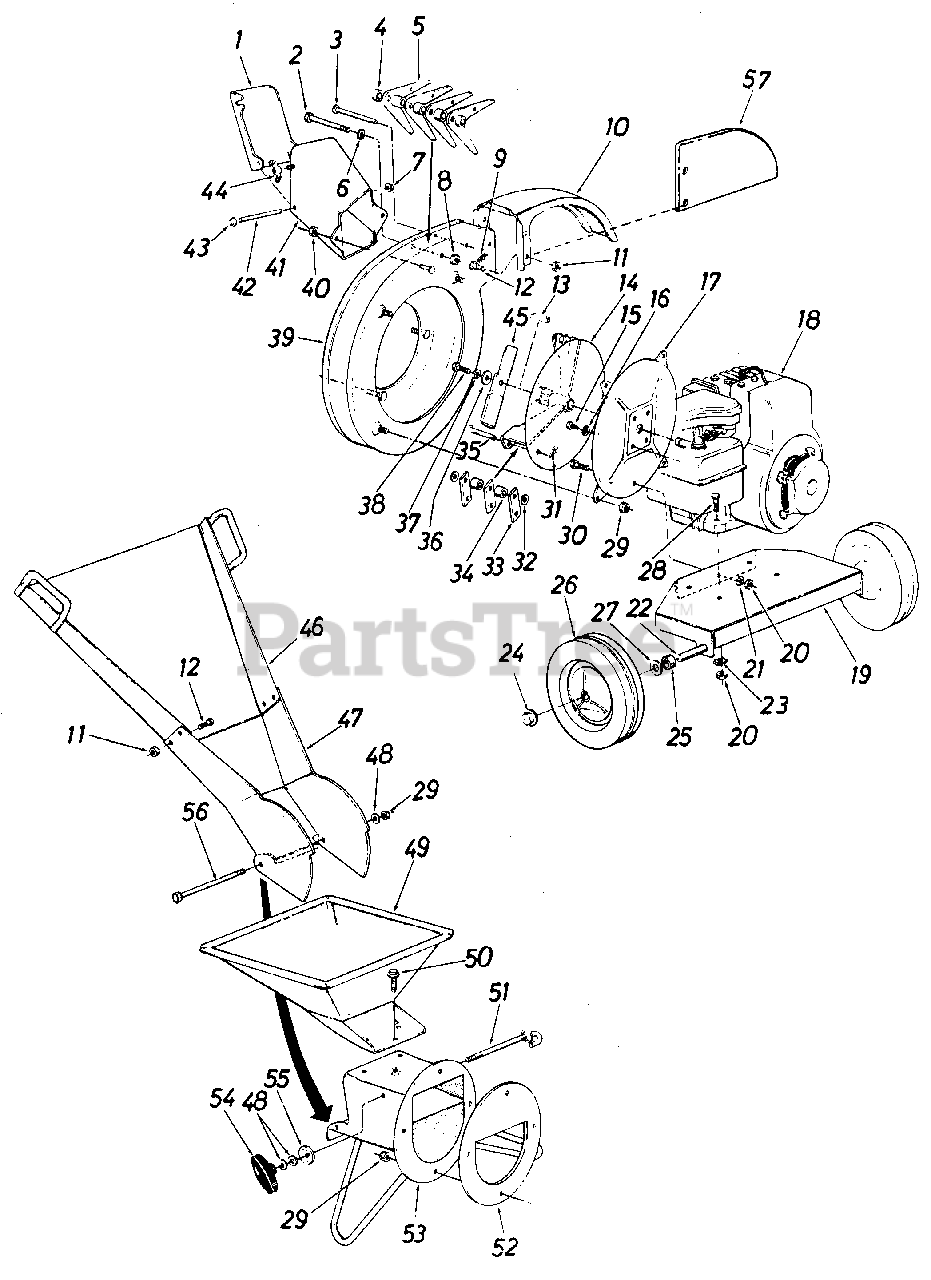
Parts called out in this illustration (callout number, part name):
1	Door Chip It
2	Hex Bolt 1/2-20 x 4.50" Lg.*
3	Clevis Pin
4	Flail Spacer 7/32" Lg.
5	Cutting Finger
6	L.-Wash. 1/2" Scr.*
7	Palnut 3/16" Dia.
8	Hex Jam Nut 1/2-20 Thd.*
9	Cotter Pin 3/32" Dia. x 3/4" Lg. *
10	Chute Deflector
11	L.-Nut 1/4-20 Thd.
12	Hex Bolt 1/4-20 x .50" Lg.*
13	Sq. Key 1/4" x 2.00" Lg.*
14	Impeller Assembly
15	Hex Bolt 5/16-24 x 3/4" Lg.*
16	L-Wash. 5/16" Scr.*
17	Hopper to Engine Mtg. Plate
18	Engine
19	Engine Mounting Plate
20	Hex Nut 5/16-24 Thd,*
21	L.-Wash. 5/16" Scr.*
22	Shaft
23	Special L.-Wash. 5/16" I.D.
24	Push Cap
25	Spacer
26	Wheel Ass'y.-Comp.
27	Fl.-Wash..50" I.D.*
28	Hex Bolt 5/16-24 x 1.50" Lg. *
29	Elastic Stopnut 5/16-18 Thd.
30	Hex Bolt 5/16-24 x .62" Lg.*
31	Cotter Pin 1/8" Dia. x 1.00" Lg.*
32	Fl-Wash..531" I.D. x937 O.D. x .09
33	Flail
34	Flail Spacer 23/32" Lg.
35	Clevis Pin .50" Dia. x 3.0" Lg.
36	Fl.-Wash. .406" I.D. x 1.25" O.D. Hdn.
37	L.-Wash. 3/8" Scr. H.D.
38	Hex Bolt 3/8-24 x 2.00" Lg. H.T.
41	Upper Guide Extension Ass'y.
42	Hinge Pin
43	Palnut 3/16" Dia.
44	Wing Nut Elastic 1/4-20 Thd.
46	Guide Extension Assembly
47	Guide Extension
48	Fl .-Wash . 5/16 " Scr. *
49	Hopper Assembly
50	Hex Wash. H d. Self-Tap Scr. 5/16-18 x .50" Lg.
51	Clamp Rod Assembly
52	Back-Up Plate
53	Inlet Guide Assembly
54	Knob Ass'y.
55	Stop Washer
56	Hex Bolt 5/16-18 x 8.38" Lg.
57	Deflector Side Plate
